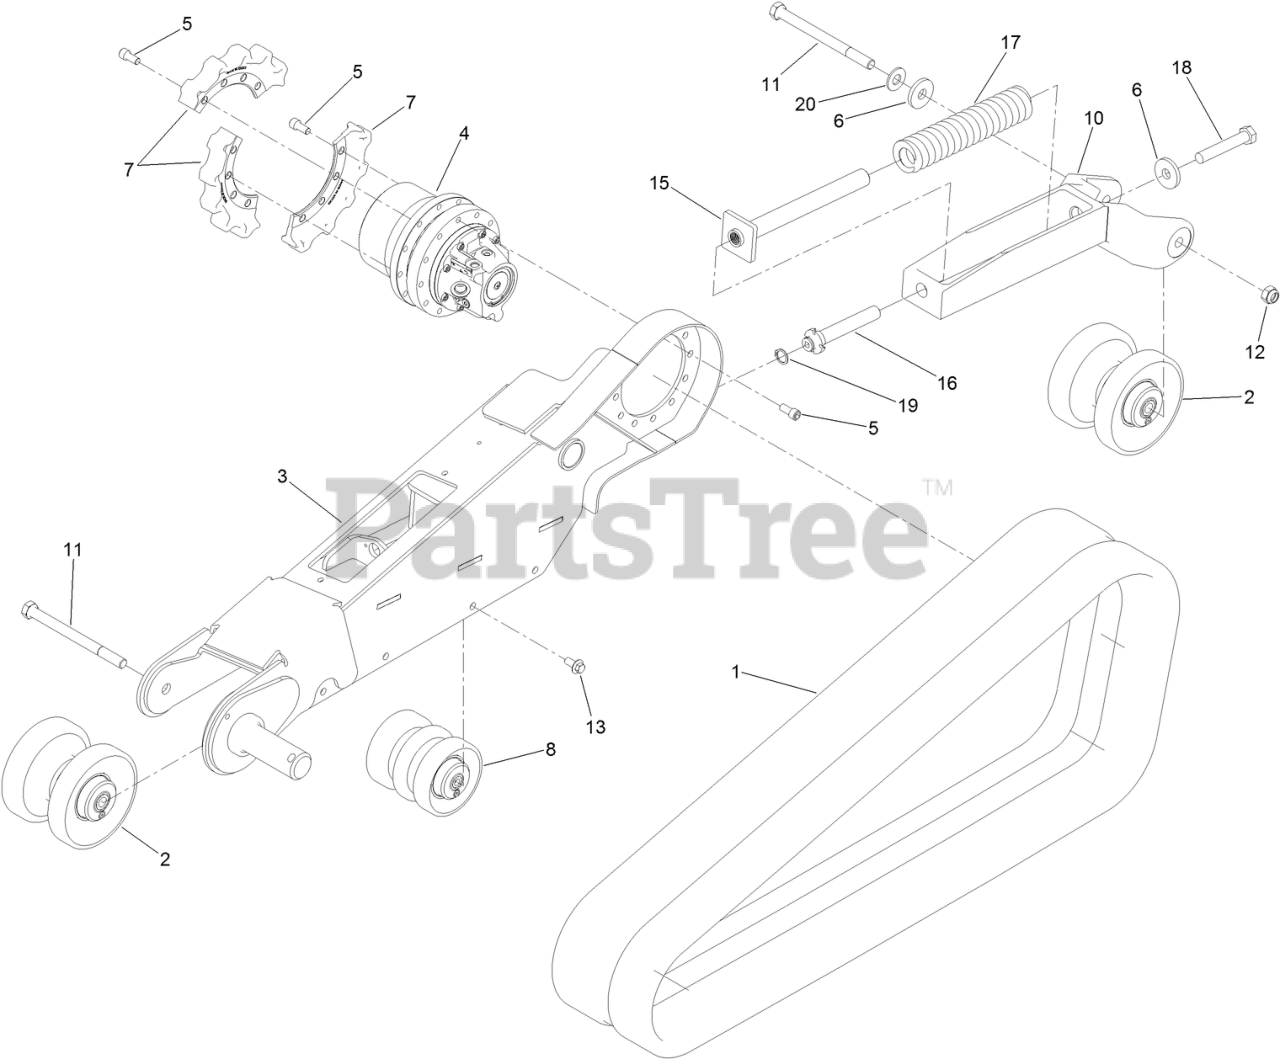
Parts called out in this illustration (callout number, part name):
1	TRACK
2	FRONT WHEEL ASM
3	RH TRACK FRAME ASM
4	DRIVE-TRACK
5	SCREW-HSH
6	WASHER-WHEEL
7	SPROCKET-DRIVE
8	ROAD WHEEL ASM
10	TENSIONER ASM
11	BOLT-HH
12	NUT-HEX
13	SCREW-HHF
15	SPRING CATCH ASM
16	SCREW-TENSIONER
17	SPRING-COMPRESSION
18	BOLT-TAP
19	RING-RETAINING, EXTERNAL
20	WASHER-PLAIN
